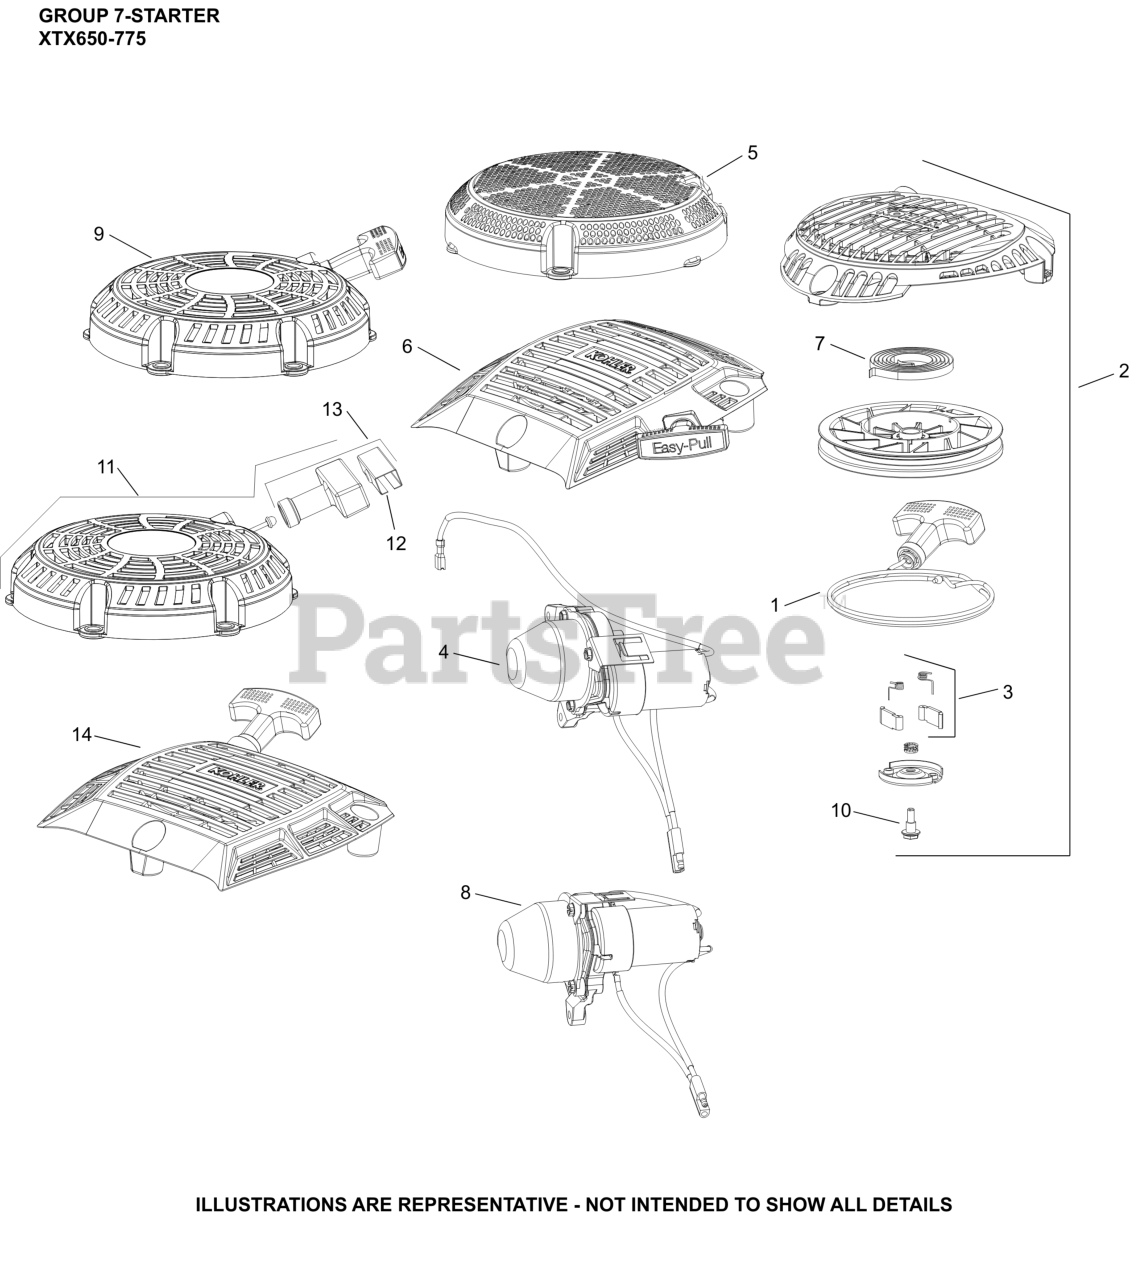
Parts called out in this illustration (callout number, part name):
1	KIT, STARTER ROPE W/HANDLE
2	STARTER ASSEMBLY, RETRACT
3	KIT, PAWL REPAIR
